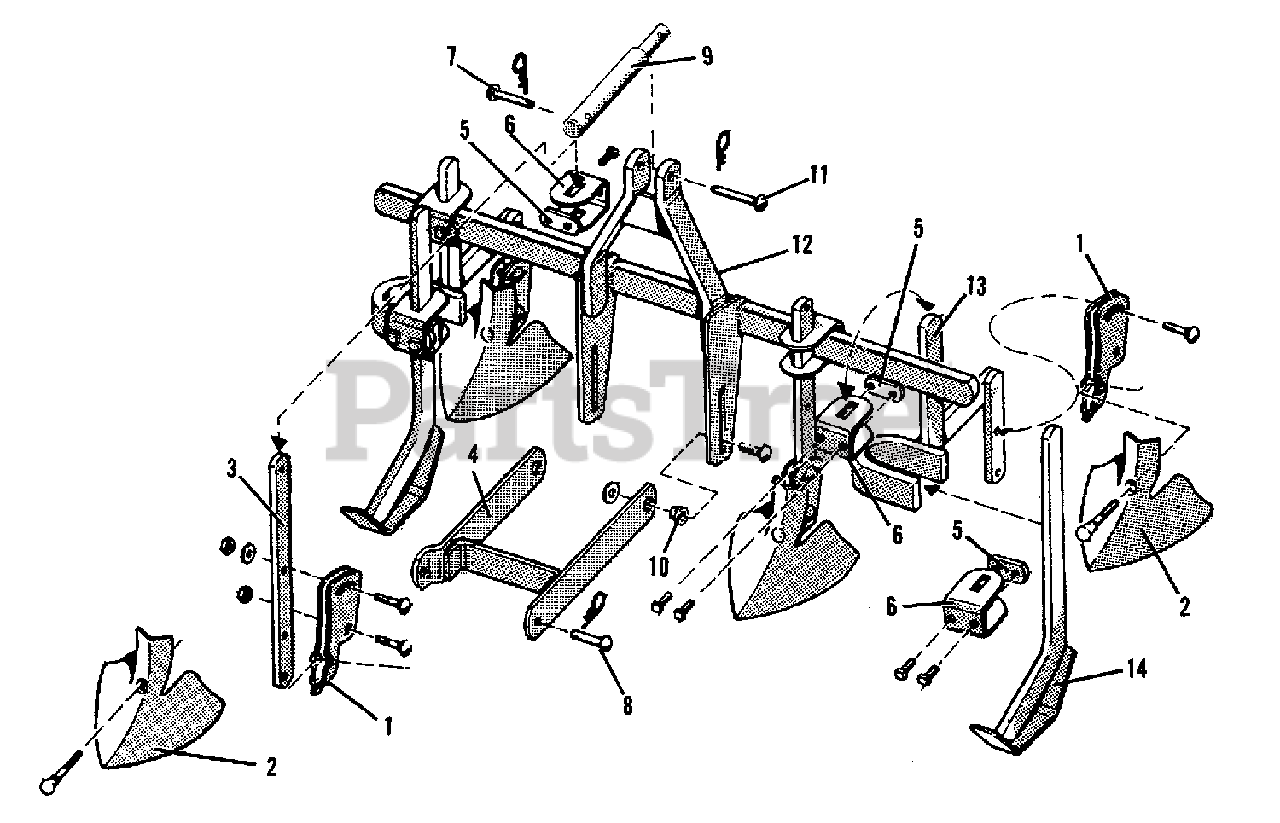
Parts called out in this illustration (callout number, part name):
1	HOLDER ASSEMBLY, Tool
1	BOLT, 3/8NC x 1-1/4
1	WASHER, Plain, 3/8
1	NUT, 3/8NC
2	SWEEP, Universal
2	BOLT, Plow, 7/16NC x 2
2	WASHER, Plain, 7/16
2	NUT, 7/16NC
3	TOOL, Standard
4	ARM ASSEMBLY
4	BOLT 7/15 NC x 1-1/2
4	WASHER, 3/8
4	LOCKWASHER, 3/8
4	NUT, 7/16NC
5	NUT, Special
6	CLAMP, Shank
7	PIN, Quick
8	PIN, Round Head
8	PIN, Quick
9	BAR, Lift
11	PIN, Quick
12	BAR ASSEMBLY, Rear Tool
13	TOOL ASSEMBLY, Standard
14	SHOE ASSEMBLY, Weld
